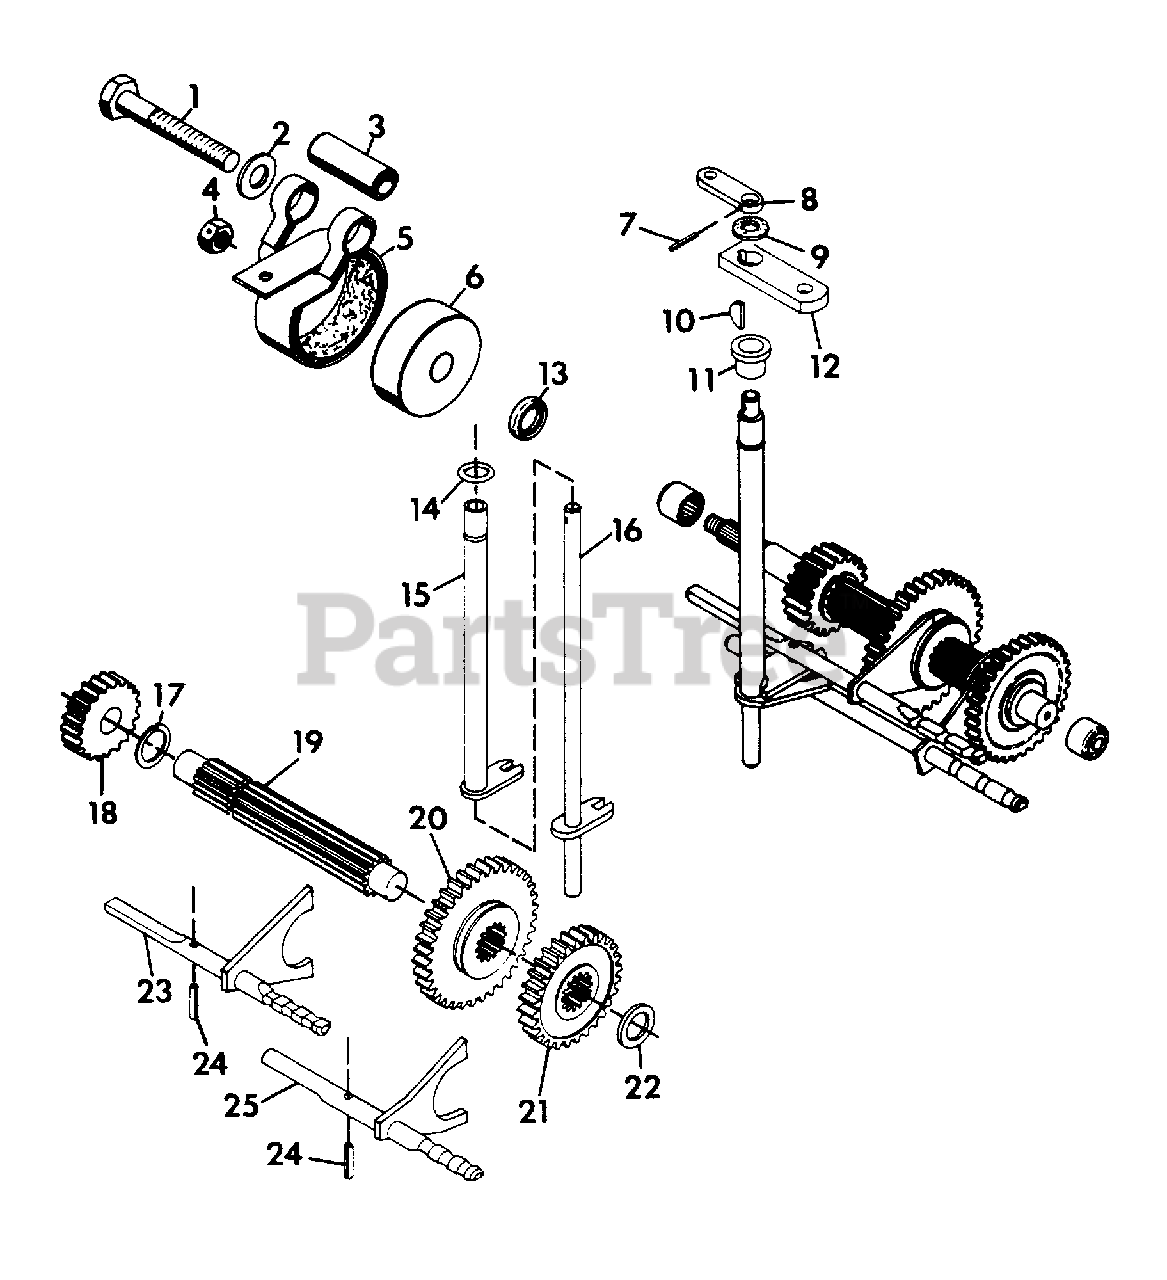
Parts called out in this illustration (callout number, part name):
1	BOLT, HEX 1/2-13X2.75
2	WASHER, FLAT .531X1.062X.095
3	BUSHING, .530X.750X2.06
4	NUT, LOCK 5/8-11
5	ASSEMBLY, BRAKE BAND
6	DRUM, BRAKE
7	PIN, SPRING .188X1.000
8	ARM, SHIFTER
9	WASHER, FELT(SPECIAL FOR TRANS.)
10	KEY, WOODRUFF .125X.375 HARD
11	BUSHING, .756X1.125X.75
12	ARM, SHIFTER
13	SEAL, OIL .750X1.254X.188
14	O-RING, 5/8X3/4X1/16
15	WELDMENT, 1ST AND 3RD SHIFTER
16	WELDMENT, 2ND AND 4TH SHIFTER
17	RING, RETAINING 1.00 SHAFT
18	GEAR, 8 DP 16 TEETH X.850
19	SHAFT, SLIDE GEAR
20	GEAR, SLIDING 10 DP 36 TEETH X.594
21	GEAR, SLIDING 10 DP 30 TEETH X.594
22	RACE, BEARING THRUST .752X1.240X.095
23	WELDMENT, RAIL SHIFT FORK 1&3 RANGE
24	PIN, SPRING .25X.75
25	WELDMENT, RAIL SHIFT FORK 2&4 RANGE
